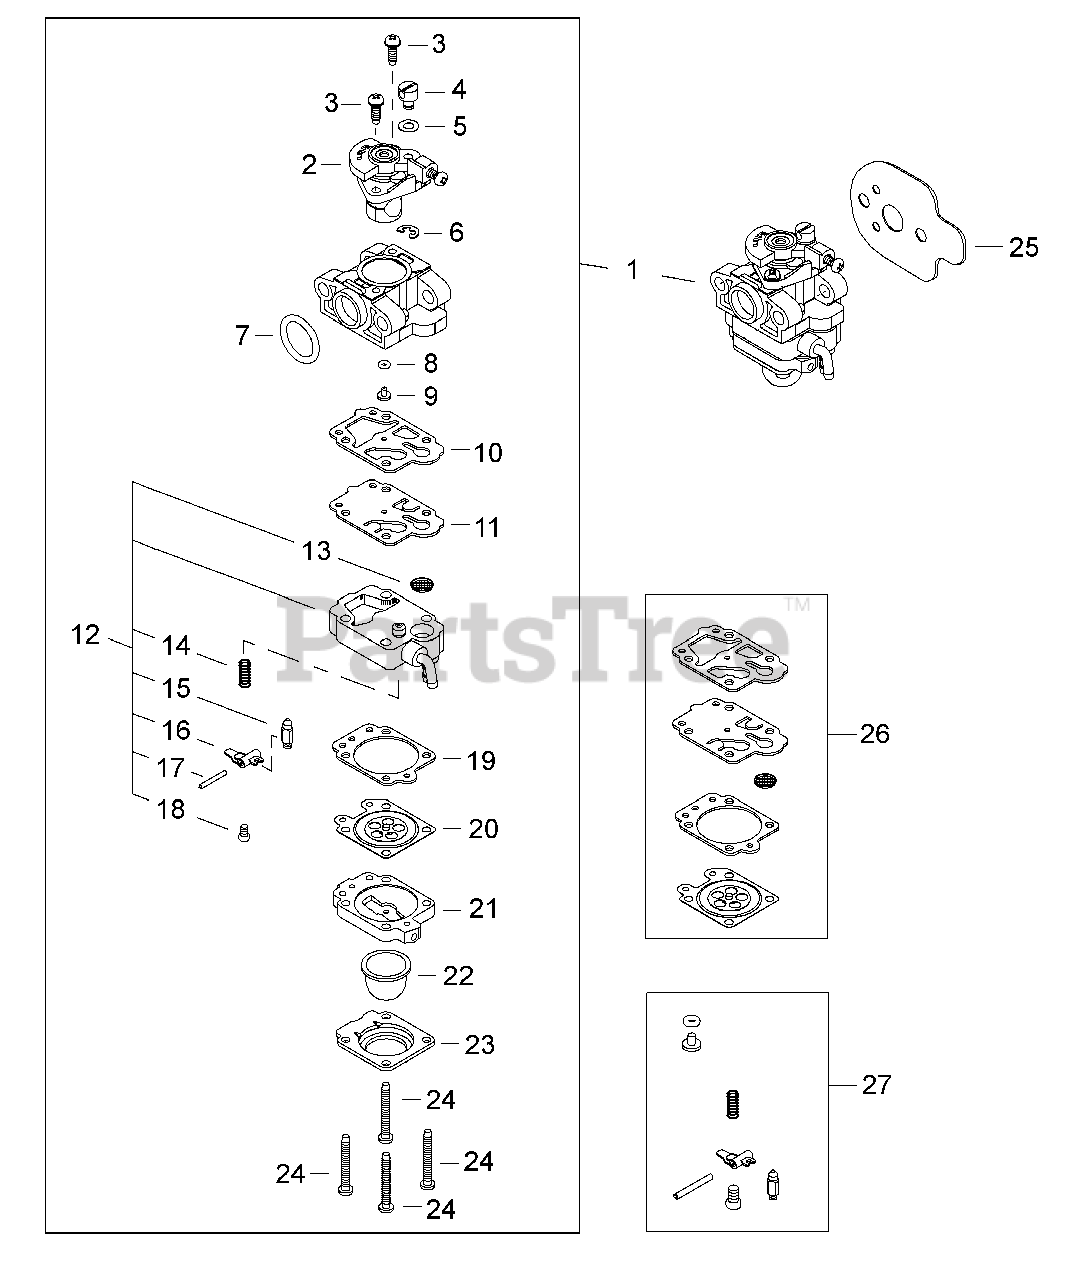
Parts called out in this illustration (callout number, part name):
1	CARBURETOR
2	VALVE ASSY, THROTTLE
3	SCREW, THROTTLE COLLAR
4	SWIVEL
5	WASHER
6	E-RING
7	O-RING 15
8	O-RING
9	JET, MAIN
10	GASKET, PUMP
11	DIAPHRAGM, PUMP
12	BODY ASSY, PUMP
13	SCREEN, FUEL INLET
14	SPRING, METERING LEVER
15	VALVE, INLET NEEDLE
16	LEVER, METERING
17	PIN, METERING LEVER
18	SCREW
19	GASKET, METERING DIAPHRAGM
20	DIAPHRAGM, METERING
21	BODY ASSY, PURGE
22	BULB, PURGE
23	RETAINER, PURGE BULB
24	SCREW
25	GASKET, INTAKE
26	GASKET / DIAPHRAGM KIT
27	VALVE KIT, INLET NEEDLE
